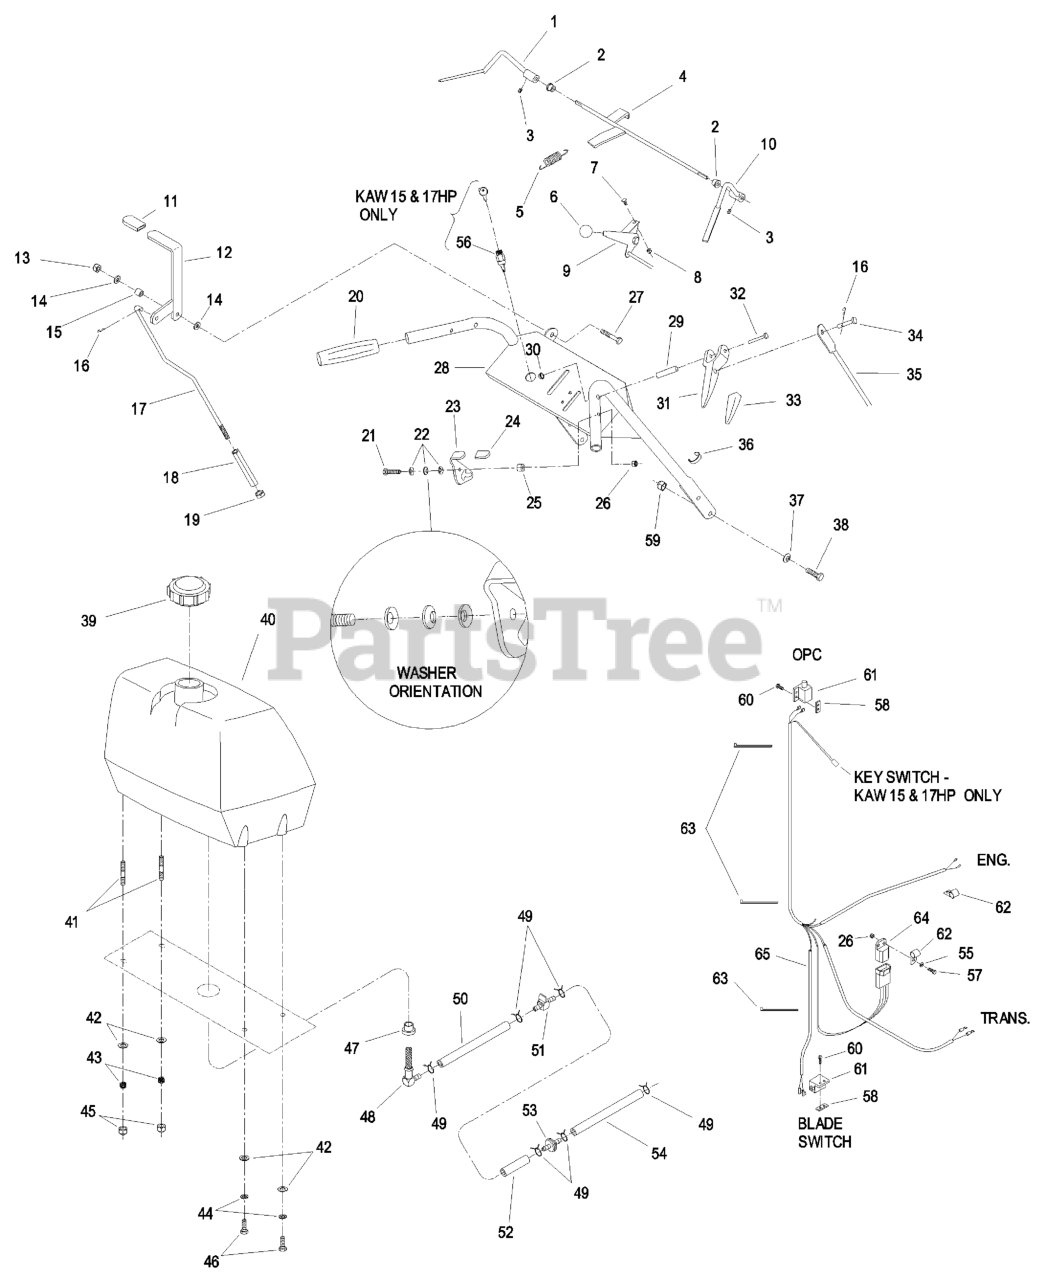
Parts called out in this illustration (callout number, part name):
1	LEVER-LH
2	BUSHING-NYLON
3	SCREW-SET
4	WLD,ROD OPC
5	SPRING-EXTENSION
6	KNOB-BALL
7	BOLT-CARR
8	LINKAGE,UPPER
9	CABLE,THROTTLE CONTROL
10	LEVER-RH
11	GRIP-LEVER
15	BUSHING-LEVER, LIFT
16	PIN-COTTER
17	LINKAGE,UPPER
18	TURNBUCKLE
22	WASHER-SPRING
24	GRIP-LATCH
29	PIN-ROLL
30	NUT-PUSH
31	DRIVE LEVER ASM
32	PIN-LEVER, DRIVE
33	GRIP-LEVER, DRIVE
34	PIN-CLEVIS
35	LINKAGE,DRIVE WHEEL
36	CLIP-CABLE
39	CAP-FUEL
41	STUD
43	SPRING-TANK, FUEL
44	WASHER-LOCK
48	ELBOW-TANK, FUEL
49	CLAMP
50	HOSE-FUEL
51	VALVE-FUEL
52	HOSE-LINE, FUEL
54	HOSE-LINE, FUEL
56	SWITCH & KEY (INCLUDES NU
58	PLATE-TAPPED
61	SWITCH-OPEN, NORMALLY
62	CLIP-LOOM
63	TIE-CABLE
64	MODULE-INTERLOCK
